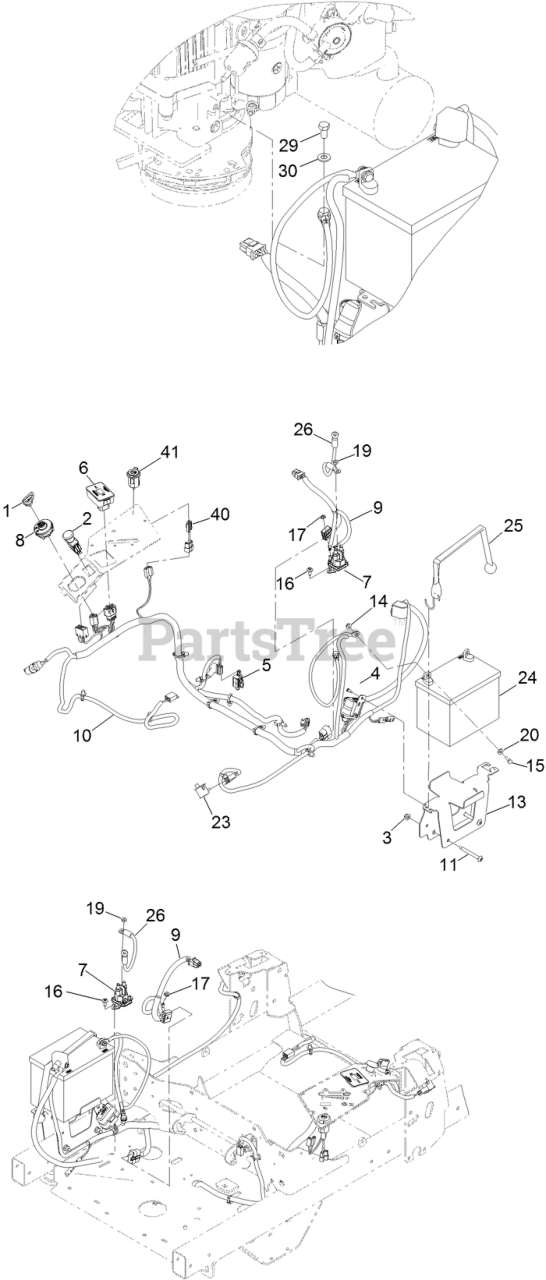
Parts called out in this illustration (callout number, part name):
1	KEY-IGNITION
2	SWITCH-PTO
3	NUT-HF, NI
4	SCREW-FORMING, THREAD
5	SWITCH
6	MODULE ASM
7	SOLENOID
8	SWITCH-IGNITION
9	ADAPTER-HARNESS, WIRE
10	HARNESS-WIRE
11	SCREW-TORX
13	TRAY-BATTERY
14	NUT-HF
15	SCREW-HH
16	SCREW-TORX
17	NUT-KEPS
19	NUT-JAM
20	WASHER-FLAT
23	SWITCH-BAIL
24	BATTERY
25	STRAP-BUNGEE
26	CABLE-BATTERY, POSITIVE
29	SCREW-HH
30	WASHER-PLAIN
40	HARNESS-WIRE, USB KIT
41	PORT-POWER, USB
